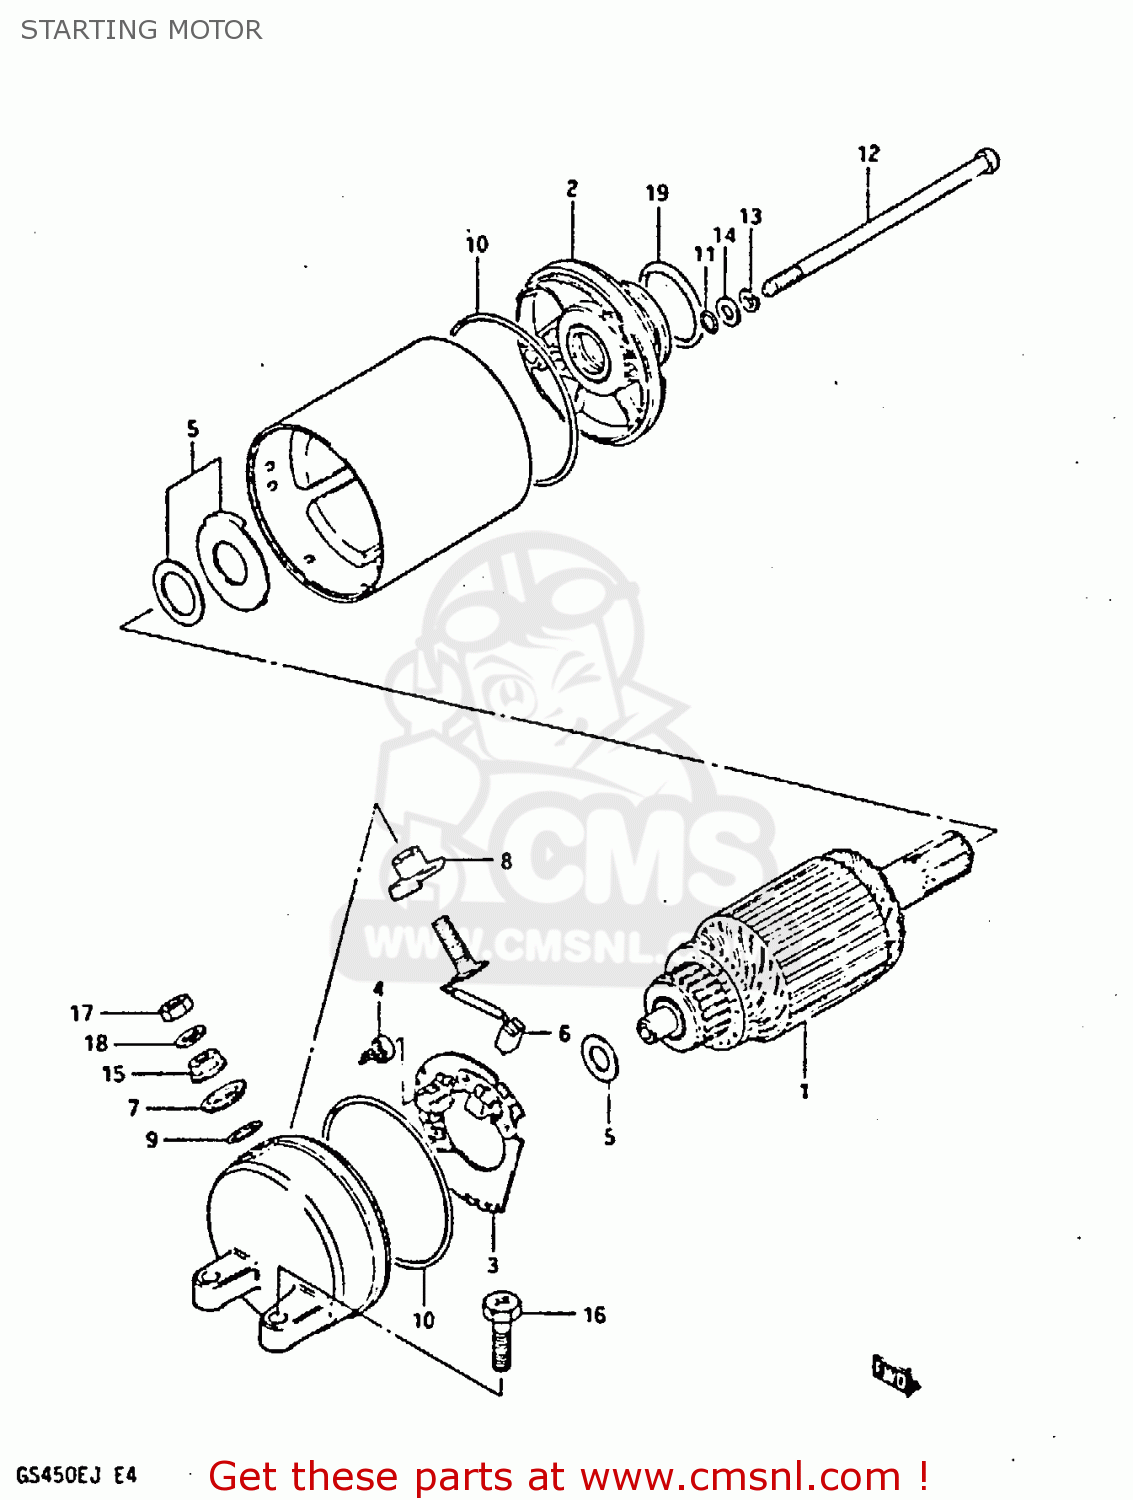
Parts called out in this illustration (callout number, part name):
1	ARMATURE
2	BRACKET SET,STARTING MOTOR
3	HOLDER,BRUSH
4	SPRING
5	SHIM SET,STARTING MOTOR
6	BRUSH SUB ASSY,STARTING MOTOR
7	BUSHING
8	BUSH,B
9	O RING
10	O RING
11	O RING
12	BOLT
13	LOCK WASHER
14	WASHER
15	NUT
16	SCREW (6X25)
17	NUT
18	WASHER,LOCK
19	O RING(D:3,ID:24.5)
